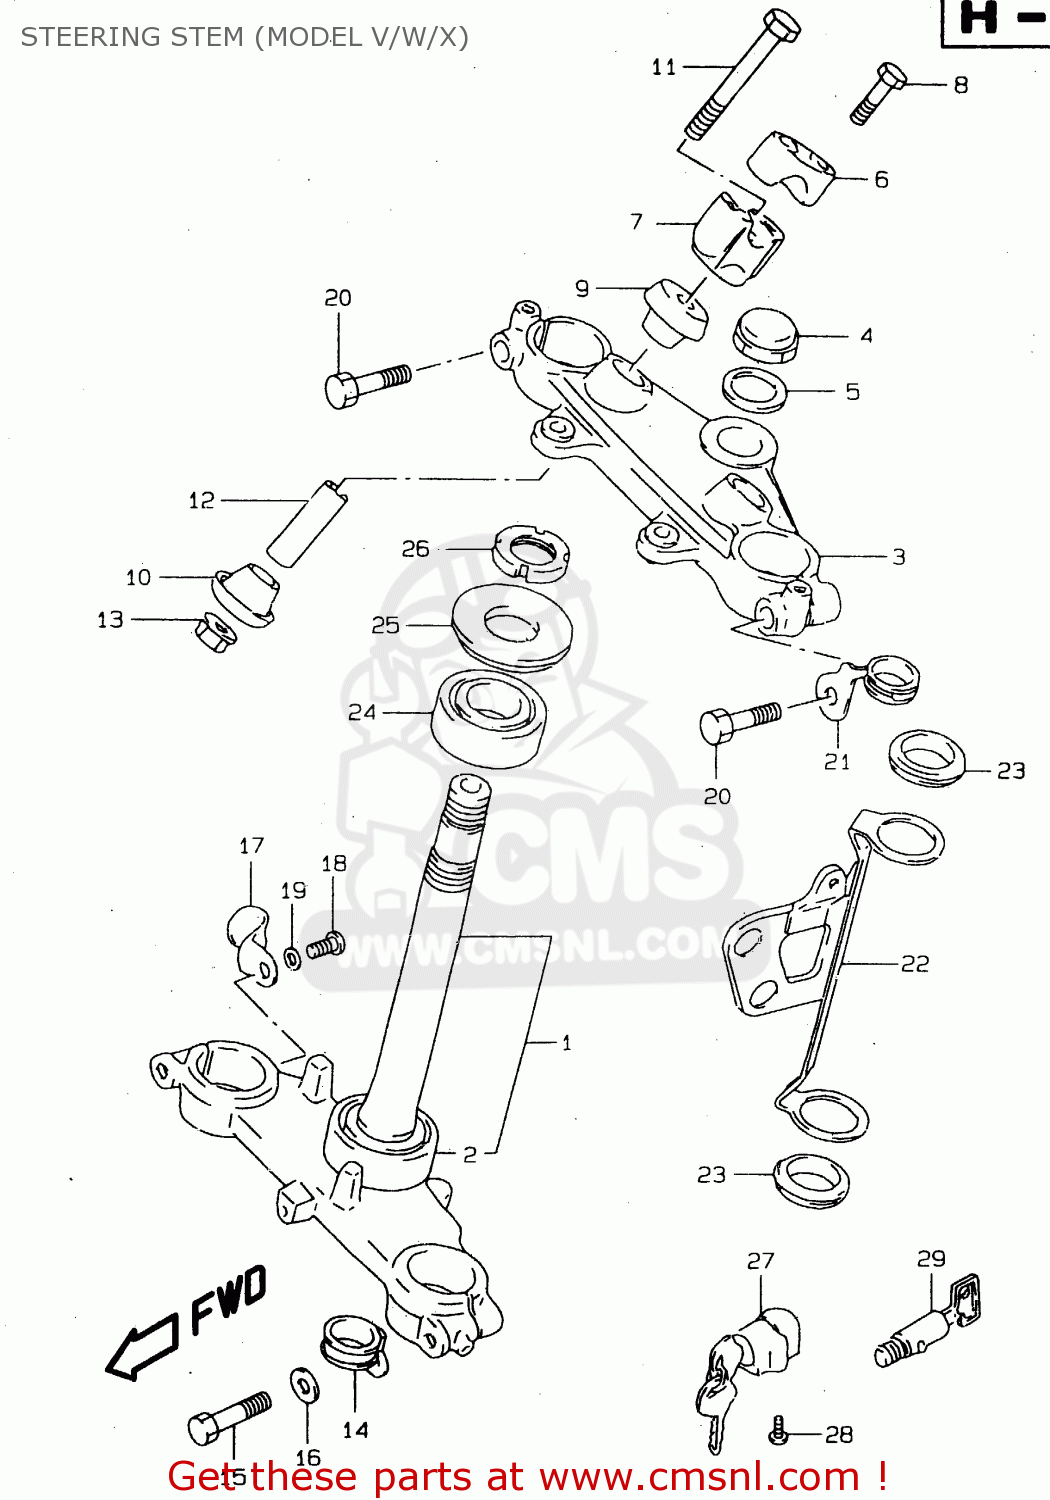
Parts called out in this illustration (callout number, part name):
1	STEM,STEERING
2	BEARING(30X55X17)
3	HEAD,STEERING STEM
4	NUT,CAP
5	WASHER
6	HOLDER,HANDLE UPR
7	HOLDER,HANDLEBAR LWR
8	BOLT
9	RUBBER,HANDLE HOLDER
10	CUSHION,RUBBER UNDER
11	BOLT,HANDLE HOLDER(10X70)
12	SPACER
13	NUT
14	CLIP,LOWER
15	BOLT,INNER TUBE FITTING
16	WASHER
17	CLIP
18	SCREW
19	WASHER,LOCK
20	BOLT
21	CLIP
22	BRACKET,HEADLAMP,R
23	CUSHION,HEADLAMP HSG BRACKET
24	BEARING(25X47X15)
25	SEAL,STEERING UPR DUST
26	NUT,STEERING
27	LOCK SET,STEERING
28	SCREW
29	LOCK ASSY,STEERING(NEIMAN)
